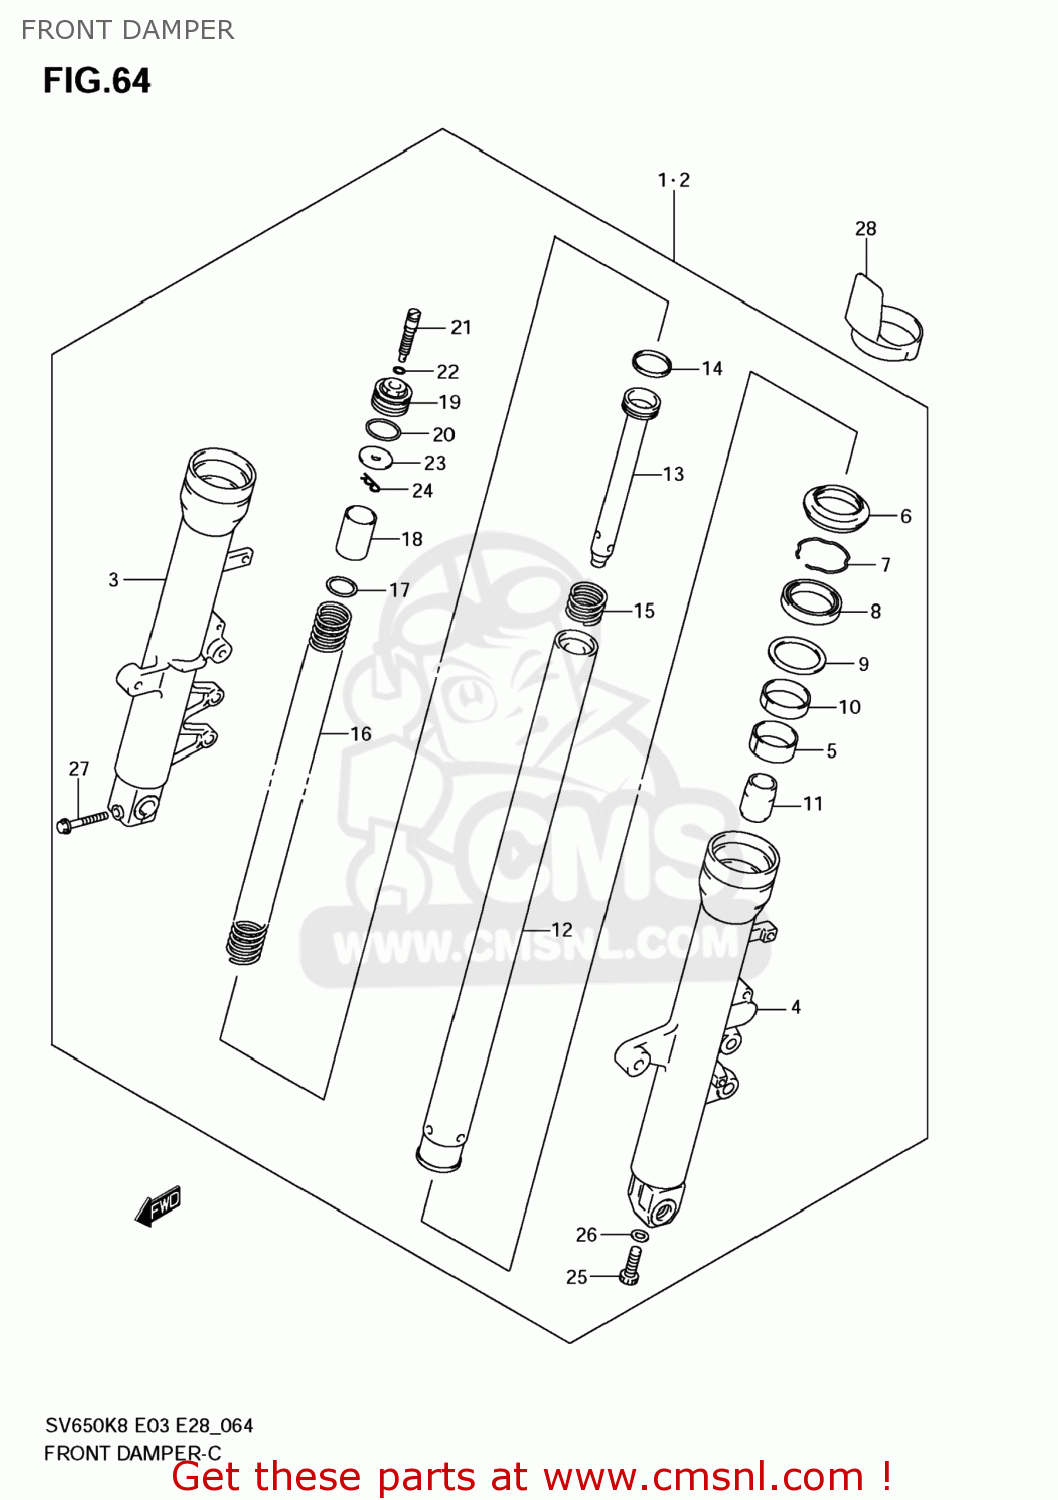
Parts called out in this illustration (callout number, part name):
1	DAMPER ASSY,FR FORK,R
2	DAMPER ASSY,FR FORK,L
3	TUBE,OUTER,R
4	TUBE,OUTER,L
5	BUSH,SLIDE
6	SEAL,DUST
7	CIRCLIP,FORK OIL SEAL
8	SEAL,OIL
9	SPACER,SEAL
10	BUSH,GUIDE
11	PIECE,OIL LOCK
12	TUBE,INNER
13	CYLINDER
14	RING,PISTON
15	SPRING,REBOUND
16	SPRING,FR
17	JOINT,SPRING
18	COLLAR,SPRING
19	BOLT,FORK
20	O RING
21	ADJUSTER BOLT,SPRING
22	O RING(D:1.9,ID:8.6)
23	SEAT,SPRING
24	PIN,SEAT SPRING
25	BOLT(8X27)
26	GASKET (NAS)
27	BOLT(8X40)
28	PROTECTOR
